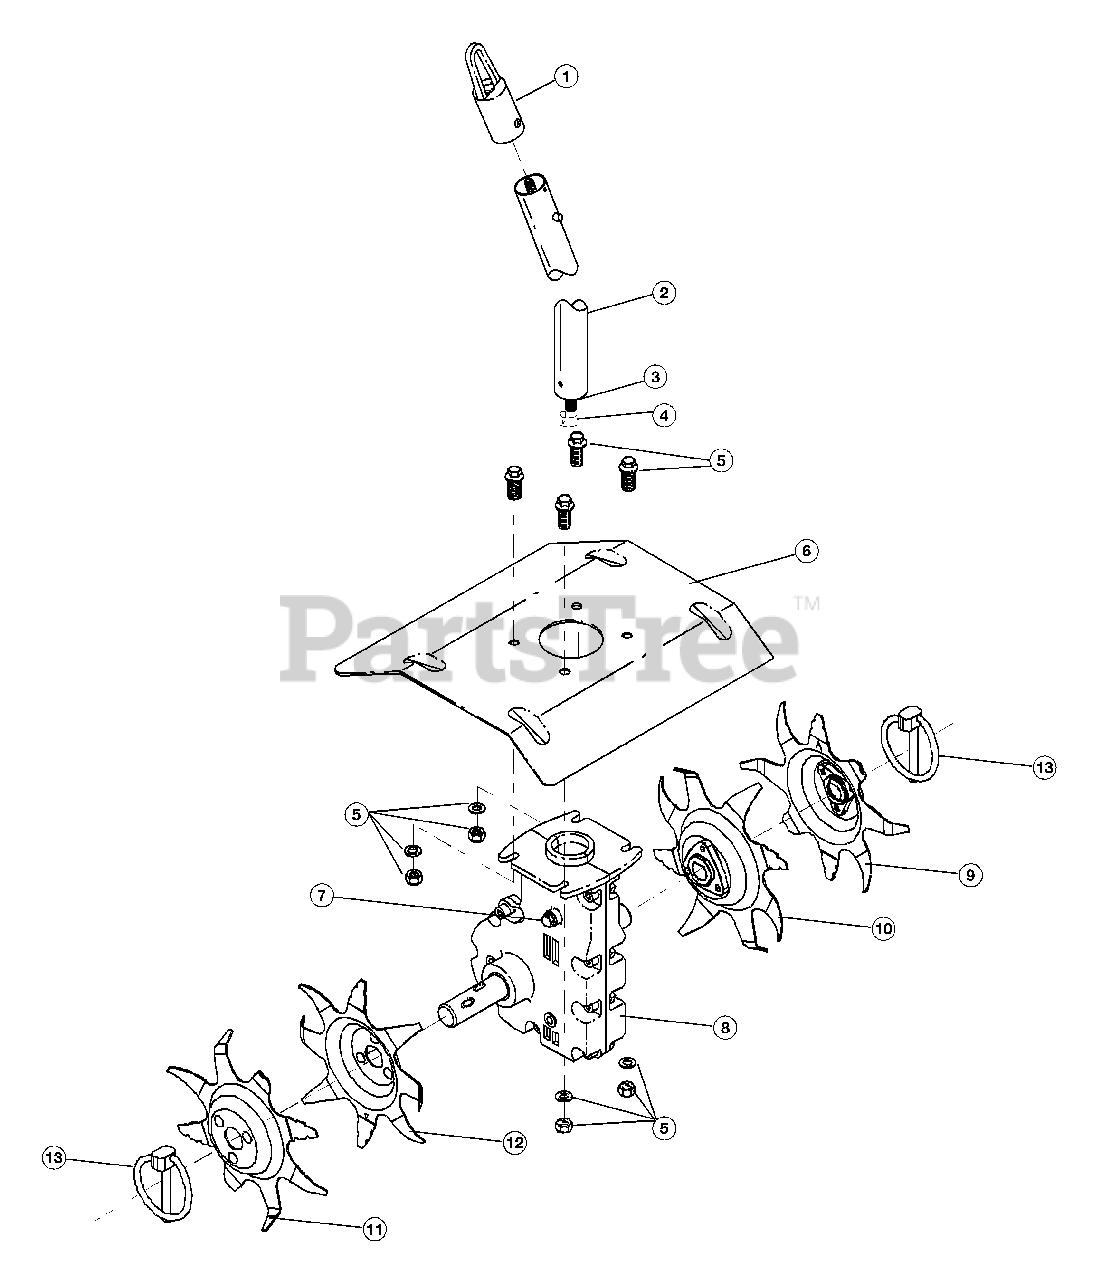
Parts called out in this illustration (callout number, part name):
1	Accessory Hanger
2	Drive Shaft Housing Assembly
3	Flexible Drive Shaft
4	Retainer Sleeve
5	Guard Mounting Hardware Set
6	Guard
7	Bolt
8	Gear Box Assembly
9	Tine OTR
10	Tine INR
11	Tine OTR
12	Tine INR
